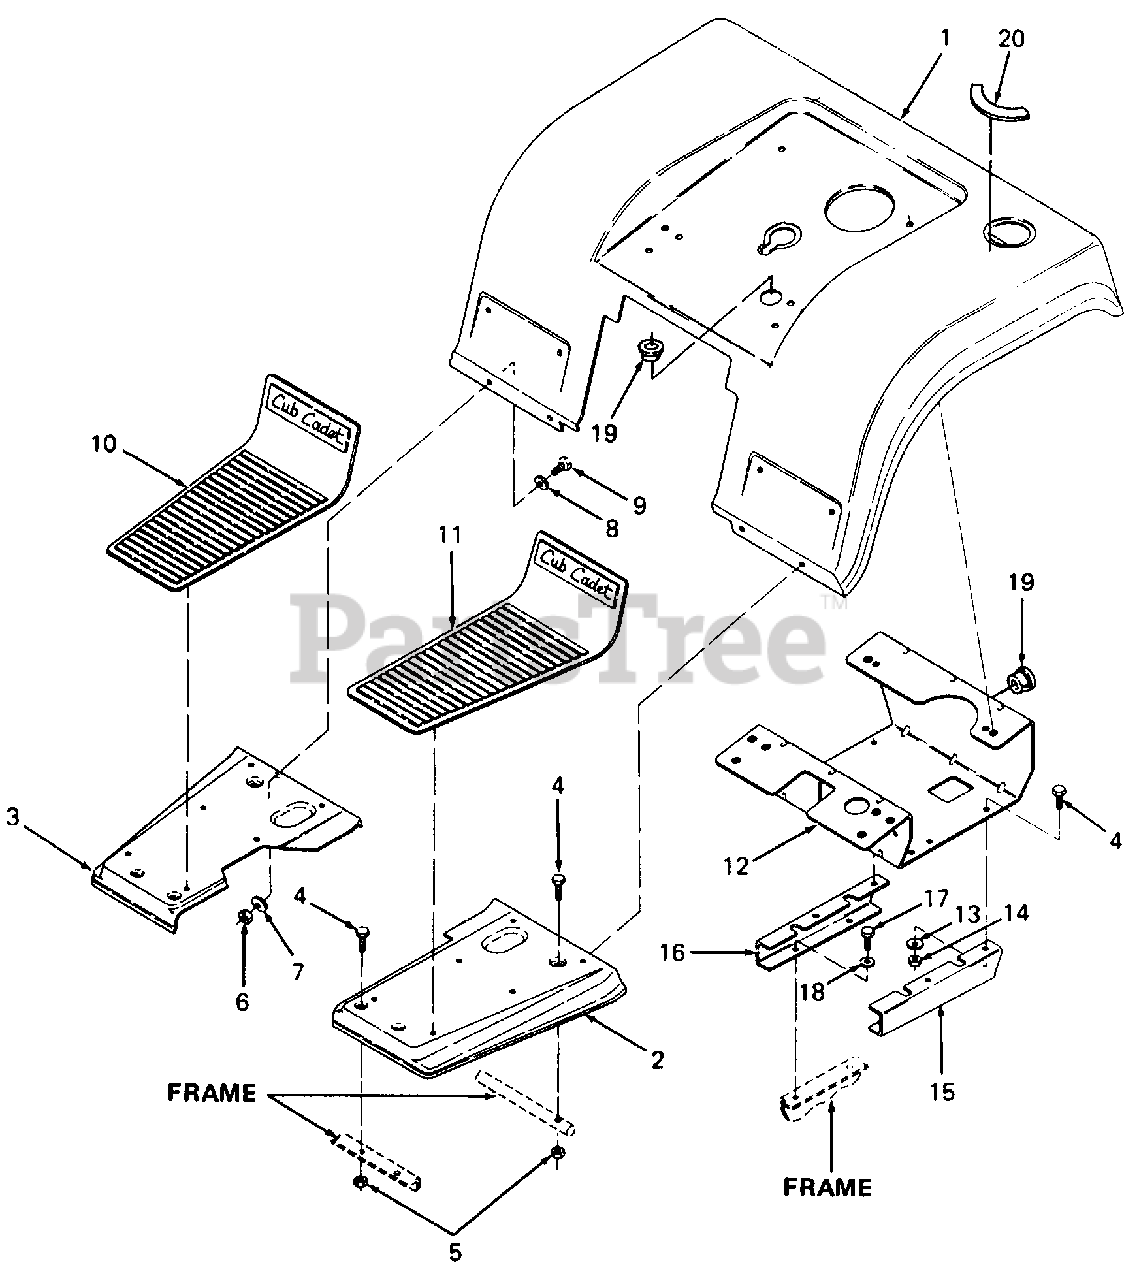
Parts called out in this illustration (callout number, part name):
5	Nut, Hex Center Lock, 5/16-18 GR5
6	Nut, Hex Patch Lock, 1/4-20
7	Washer, Bell, .265 X .75 X .062 Thk
8	Washer, Flat, .281 X .73 X .063 Thk
9	Screw, Hex Cap, 1/4-20 X .50 Lg GR5
10	Foot Pad - RH
11	Foot Pad - LH
13	Washer, Bell, .345 X .88 X .060 Thk
14	Nut, Hex, 5/16-18 GR5
15	Support Bracket, Fender - LH
16	Support Bracket, Fender - RH
17	Screw, Hex Cap, 5/16-18 X .62 Lg GR5
18	Washer, Flat, .34 X .68 X .062 Thk
19	Bushing, Snap
20	Label, Diesel Fuel Only
